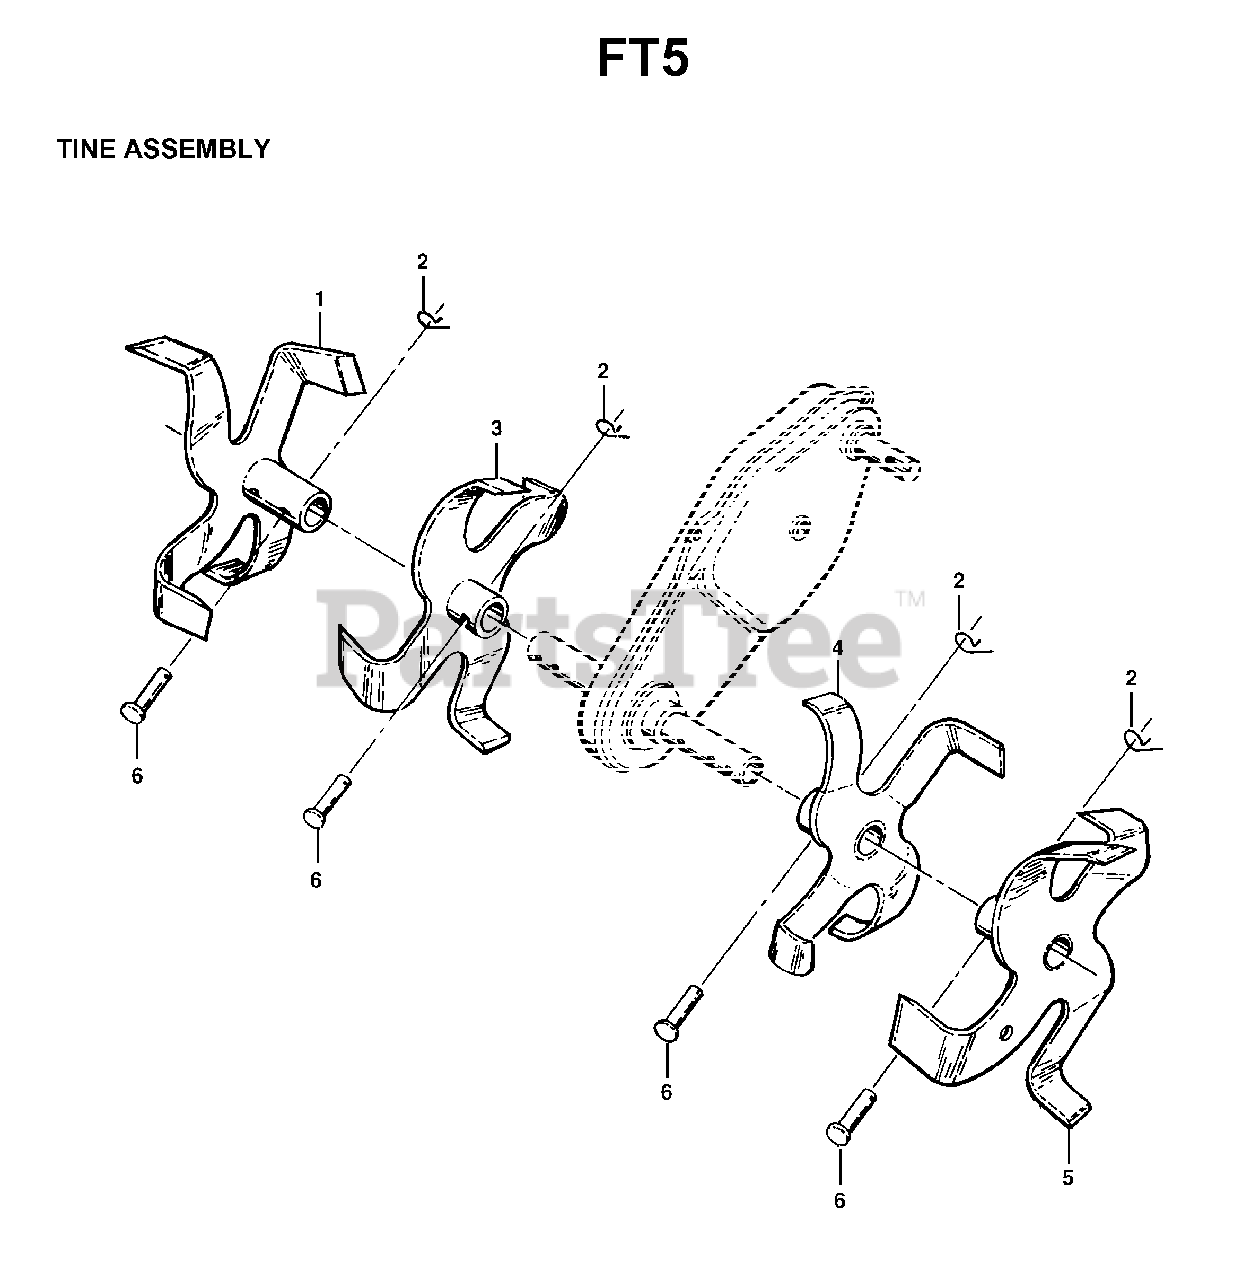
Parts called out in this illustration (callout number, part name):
1	RP TINE
2	SPRING RETAINER
3	RP TINE
4	RP TINE
5	RP TINE
